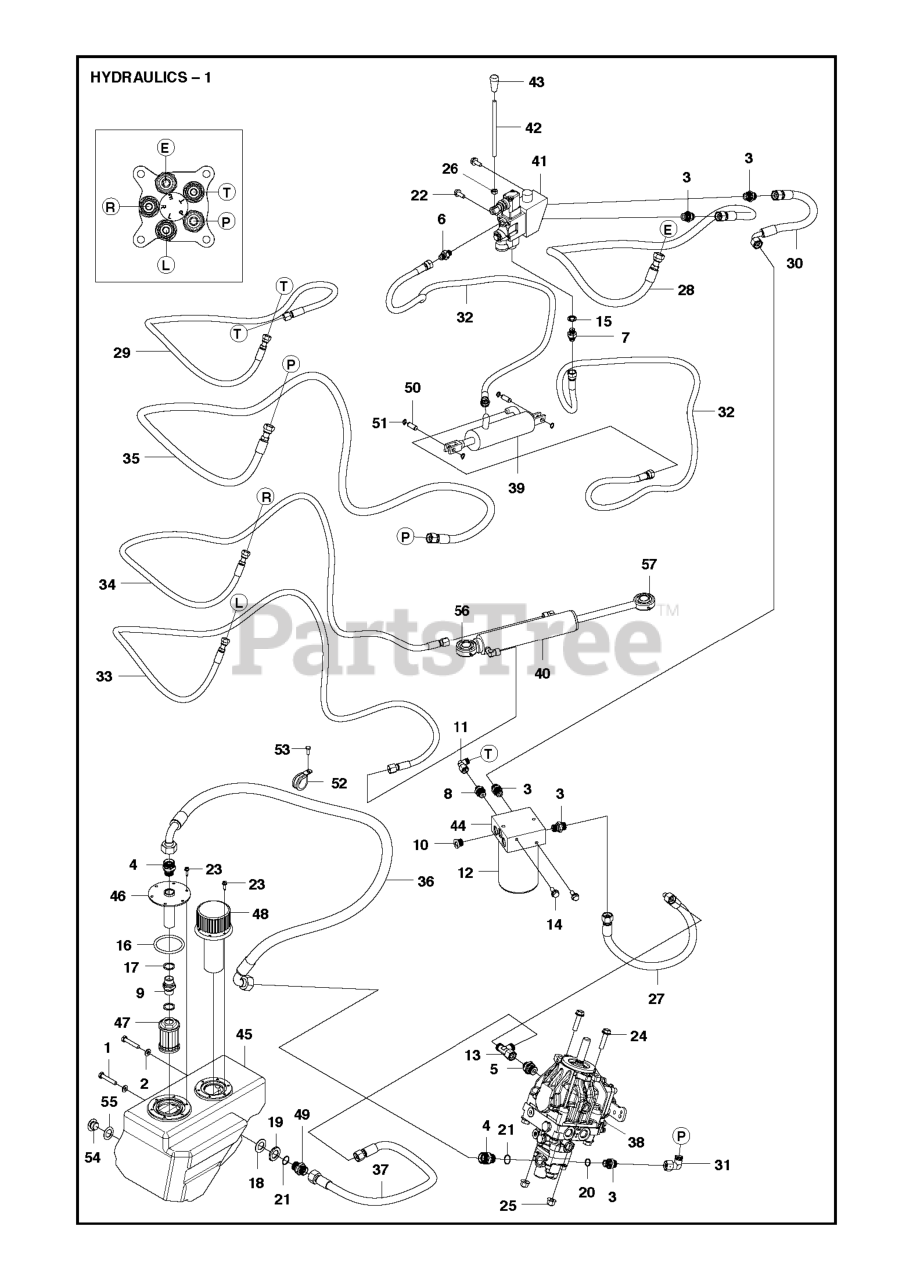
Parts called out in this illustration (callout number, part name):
1	SCREW
2	WASHER BRB 8.4X17
9	PIPE FITTING G STRAIGHT 1/2-1/
15	O-RING 47.2X5.7 NITRIL
16	O-RING 61.2X5.7 NITRIL
20	REPL BY 740 48 14-02
26	NUT
47	FILTER PUMP SUCTION, AWD
51	RETAINING RING SGA 10
52	HOSE CLAMP
53	SCREW
